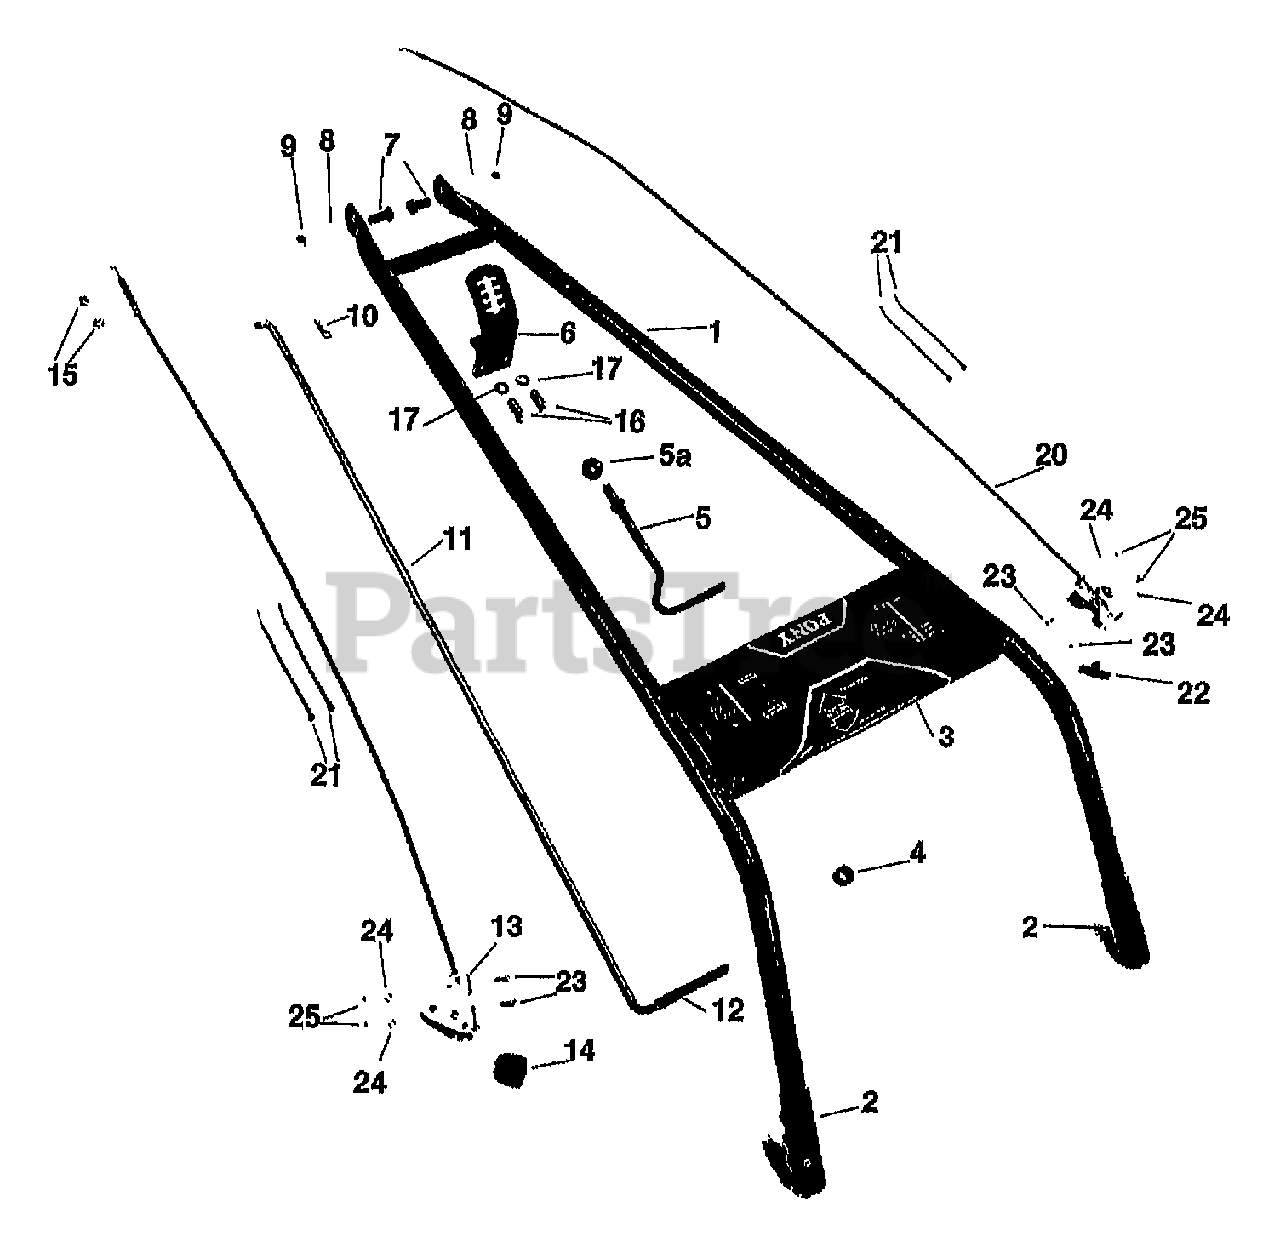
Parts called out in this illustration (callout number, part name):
1	ASSM-HANDLEBAR P4 (INCL. 2-5A)
2	GRIP-HANDLEBAR
3	DECAL-CONTROL PANEL
4	GROMMET-PLASTIC
5	ASSM-STUD H/B
5A	WASHER-1.0X.38X.375
6	PLATE-HANDLEBAR ADJUST
7	SCR-HH 3/8-16X1.0 G5 ZP
8	WASHER-FLAT 3/8 SAE (HANDLEBAR ATTACHMENT)
9	NUT-LOCK 3/8-16 NYLON ZP (HANDLEBAR ATTACHMENT)
10	PIN-CLIP .08
11	ASSM-DR CONTROL ROD (INCL. GRIP, #9198)
11	ROD-CONTROL
12	GRIP-CONTROL ROD
13	KIT-WHL DRIVE CABLE - COMPLETE (INCL. 14,15, 21,23,24,25)
14	KNOB-WHEEL DRIVE CABLE
15	NUT-HEX 5/16-24
16	SCR-HH 3/8-16X.75 G5 ZP
17	WASHER-LK .375 @ DEPL
20	CABLE-THROTTLE - COMPLETE (INCL. 22) (DOES NOT INCL. 23-25)
21	TIE-RED (PLASTIC)(TO SECURE CABLES TO HANDLEBARS)
22	KNOB-THROTTLE CABLE
23	SCR-RH M10-32X.5 MACH
24	WASHER-LK M10
25	NUT-HH M10-32X.125
